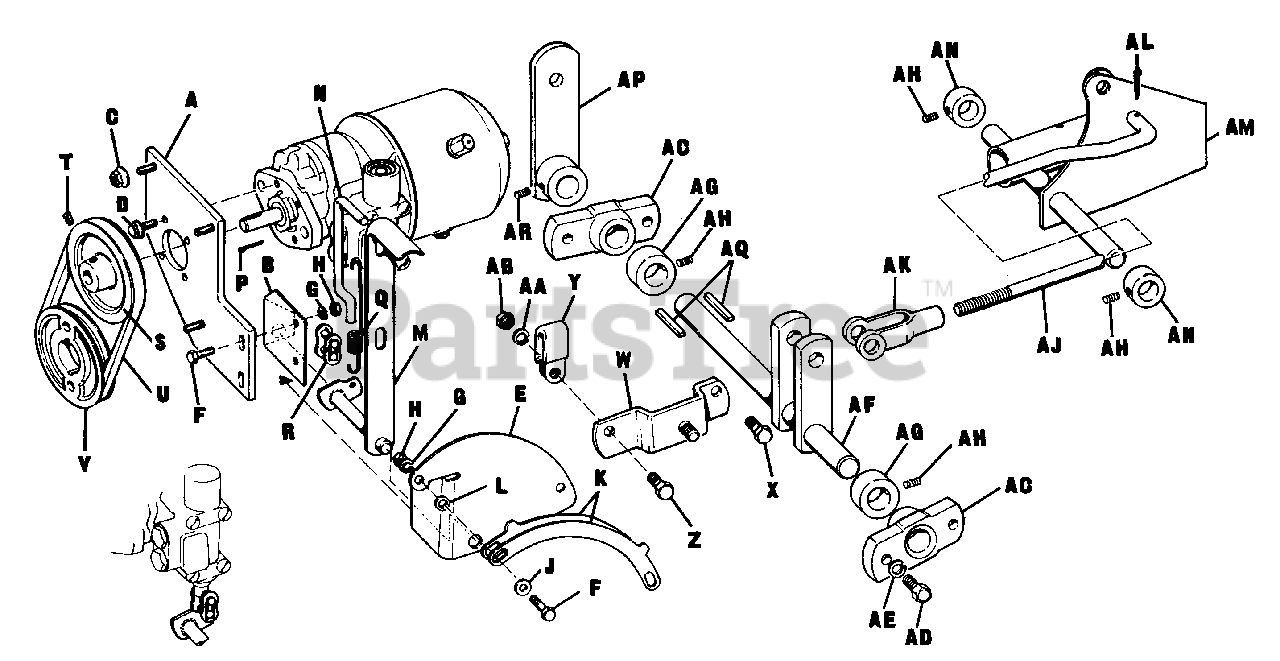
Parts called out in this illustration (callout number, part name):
A	Pump Support Assembly
B	Angle Bracket
C	Hex. Nut, Whiz Lock, 5/16"-18
D	Hex. Cap Screw, Whiz Lock, 1/4"-20 x 3/4"
F	Hex. Cap Screw, 1/4"-20 x 3/4"
G	Lock Washer, 1/4"
H	Full Hex. Nut, 1/4"-20
J	Plain Washer, 1/4"
K	Stop Plate
M	Lever Assembly
N	Latch Rod
P	Cotter Pin, 3/32" x 5/8"
R	Connecting Link
S	Pump Pulley
T	Set Screw, 5/16"-18 x 5/16"
V	Drive Pulley
W	Pivot Bar Assembly
X	Hex. Cap Screw, 5/16"-18 x 1"
Y	Hose Clamp
Z	Hex Cap Screw, 1/4"-20 x 1"
AA	Lock Washer, 1/4"
AB	Full Hex. Nut, 1/4"-20
AC	Lift Lever Bearing
AD	Hex. Cap Screw, 3/8"-16 x 7/8"
AE	Lock Washer, 3/8"
AF	Lift Shaft Assembly
AG	Set Collar
AH	Set Screw, 5/16"-18 x 5/16"
AK	Adj. Yoke End
AL	Cotter Pin, 1/8" Dia. x 1"
AM	Tiller Lift Assembly
AN	Set Collar
AP	Front Lift Lever Assembly
AR	Set Screw, 5/16"-18 x 1/4"
